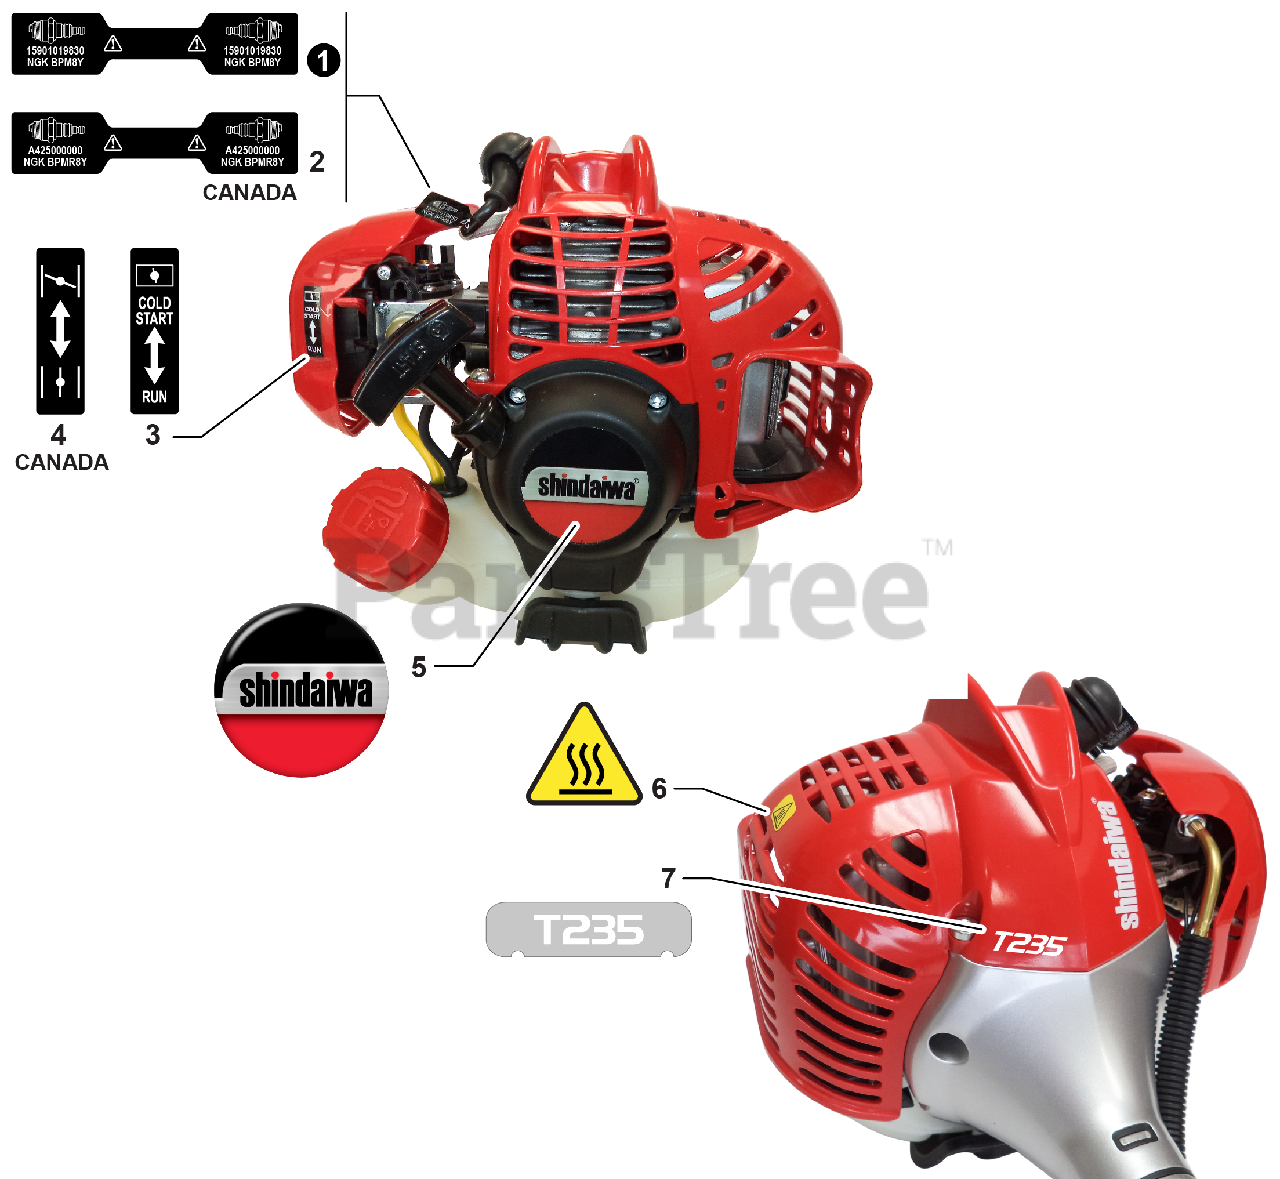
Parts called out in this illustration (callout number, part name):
1	LABEL, SPARK PLUG - BPM8Y
2	LABEL, SPARK PLUG - BPMR8Y
3	LABEL, CHOKE
4	LABEL, CHOKE
5	LABEL, SHINDAIWA
6	LABEL, CAUTION - HOT
7	LABEL - MODEL T235
